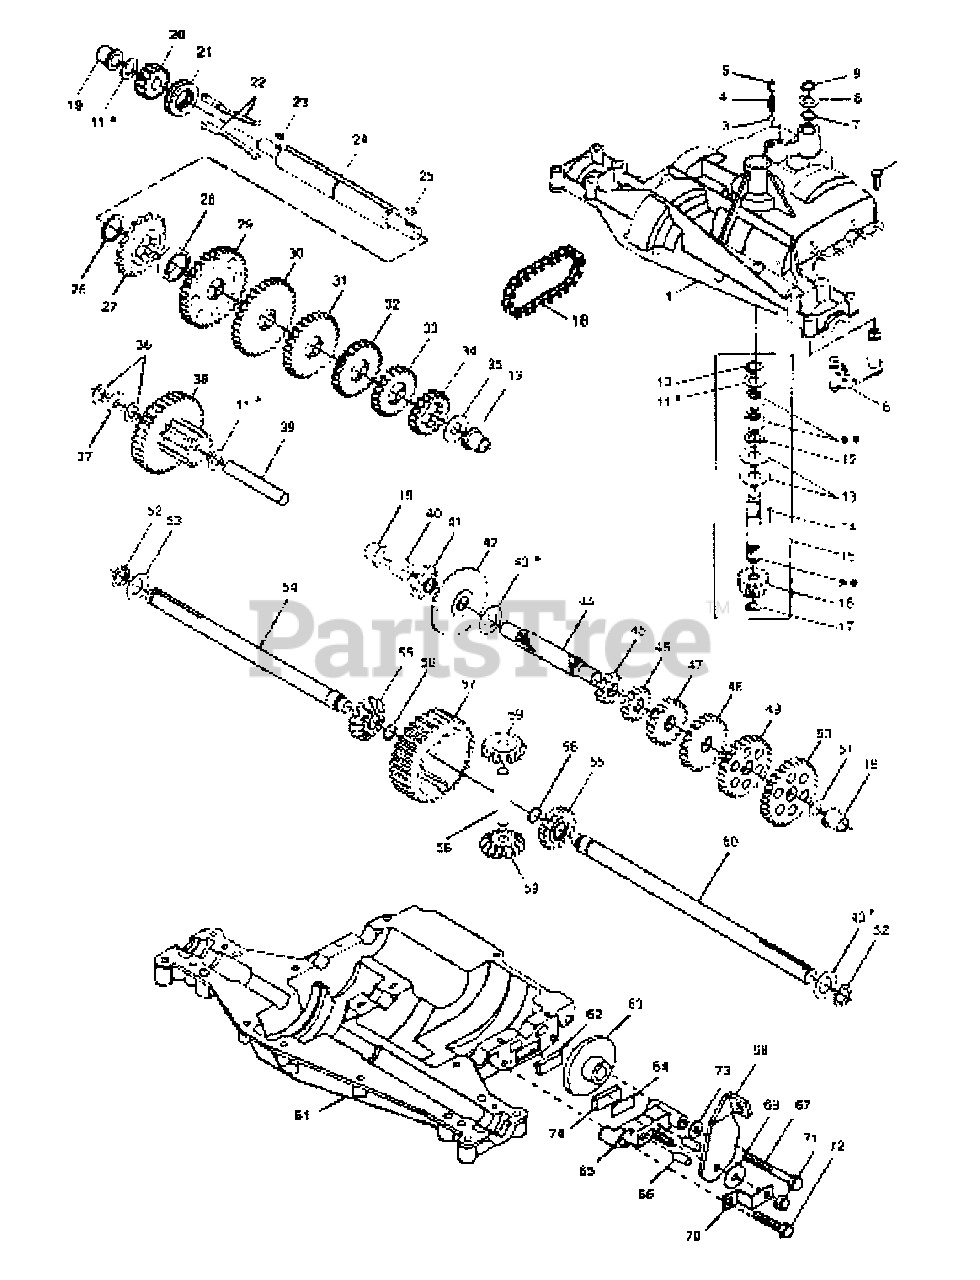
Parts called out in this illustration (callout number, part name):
1	Housing, Upper
2	Screw, Tapping, Lg. 1/4-20 x .734
3	Ball, Detent
4	Spring, Detent
5	Screw, Set
6	Assembly, Shifter
8	Washer, Plain .505 x .942 x .006
8	Washer, Plain .505 x .942 x .010
8	Washer, Plain .505 x .942 x .015
8	Washer, Plain .505 x .942 x .020
8	Washer, Plain .505 x .942 x .026
8	Washer, Plain .505 x .942 x .030
8	Washer, Plain .505 x .942 x .040
9	Ring, Retaining
10	Ring, Retaining
11	Washer, Plain .632 x 1.00 x .010
11	Washer, Plain .632 x 1.00 x .020
11	Washer, Plain .632 x 1.00 x .026
11	Washer, Plain .632 x 1.00 x .031
11	Washer, Plain .632 x 1.00 x .036
11	Washer, Plain .632 x 1.00 x .041
11	Washer, Plain .632 x 1.00 x .046
11	Washer, Plain .632 x 1.00 x .050
11	Washer, Plain .632 x 1.00 x .060
11	Washer, Plain .632 x 1.00 x .082
13	Washer, Plain .632 x 1.38 x .046
14	Key, Woodruff #9
15	Assembly, Kit, Input Shaft
16	Pinion, Bevel, 14 Teeth
17	Ring, Retaining
18	Chain, 24 Pitches
19	Bearing, Flange
20	Gear, Spur, 14 Teeth
21	Collar, Clutch
22	Key, Clutch
23	Key, Woodruff
24	Shaft, Intermediate
25	Key, Woodruff #61
26	Ring, Retaining
27	Sprocket, 18 Teeth
29	Gear, Spur, 37 Teeth
30	Gear, Spur, 35 Teeth
31	Gear, Spur, 30 Teeth
32	Gear, Spur, 25 Teeth
33	Gear, Spur, 22 Teeth
34	Gear, Spur, 19 Teeth
35	Washer, Plain .640 x 1.37 x .061
36	Washer, Plain .632 x 1.00 x .026
37	Spacer .630 x 1.00 x .169
38	Assembly, Gear, Combination 12 Teeth and 35 Teeth
39	Shaft, Idler
40	Spacer .635 x.875 x .755
41	Sprocket, 9 Teeth
42	Gear, Bevel, 42 Teeth
43	Washer, Plain .758 x 1.12 x .010
43	Washer, Plain .758 x 1.12 x .015
43	Washer, Plain .758 x 1.12 x .020
43	Washer, Plain .758 x 1.12 x .025
43	Washer, Plain .758 x 1.25 x .020
43	Washer, Plain .758 x 1.25 x .025
43	Washer, Plain .758 x 1.25 x .031
43	Washer, Plain .758 x 1.25 x .035
43	Washer, Plain .758 x 1.25 x .040
43	Washer, Plain .758 x 1.25 x .045
43	Washer, Plain .758 x 1.25 x .050
43	Washer, Plain .758 x 1.25 x .055
43	Washer, Plain .758 x 1.25 x .062
44	Shaft, Drive
45	Gear, Spur, 12 Teeth
46	Gear, Spur, 15 Teeth
47	Gear, Spur, 20 Teeth
48	Gear, Spur, 25 Teeth
49	Gear, Spur, 28 Teeth
50	Gear, Spur, 31 Teeth
51	Washer, Plain .632 x 1.00 x .060
52	Seal, Felt
53	Washer, Plain .758 x 1.25 x .062
54	Axle, L.H.
55	Gear, Miter, 15 Teeth
56	Ring, Retaining
57	Gear, Spur, 32 Teeth
58	Shaft, Cross
59	Gear, Miter, 15 Teeth
60	Axle, R.H.
61	Housing, Lower
62	Puck, Friction
63	Disc, Brake
65	Jaw, Brake
66	Pin, Dowel
67	Screw, Tapping, Lg. 5/16-18 x 2.25
68	Lever, Actuating
69	Washer, Plain .321 x 1.00 x .055
70	Bracket, Anti-Rotation
71	Locknut 5/16-24
72	Screw, Tapping, Lg. 5/16-18 x 1.44
73	Washer, Plain .343 x .81 x .059
74	Puck, Friction
